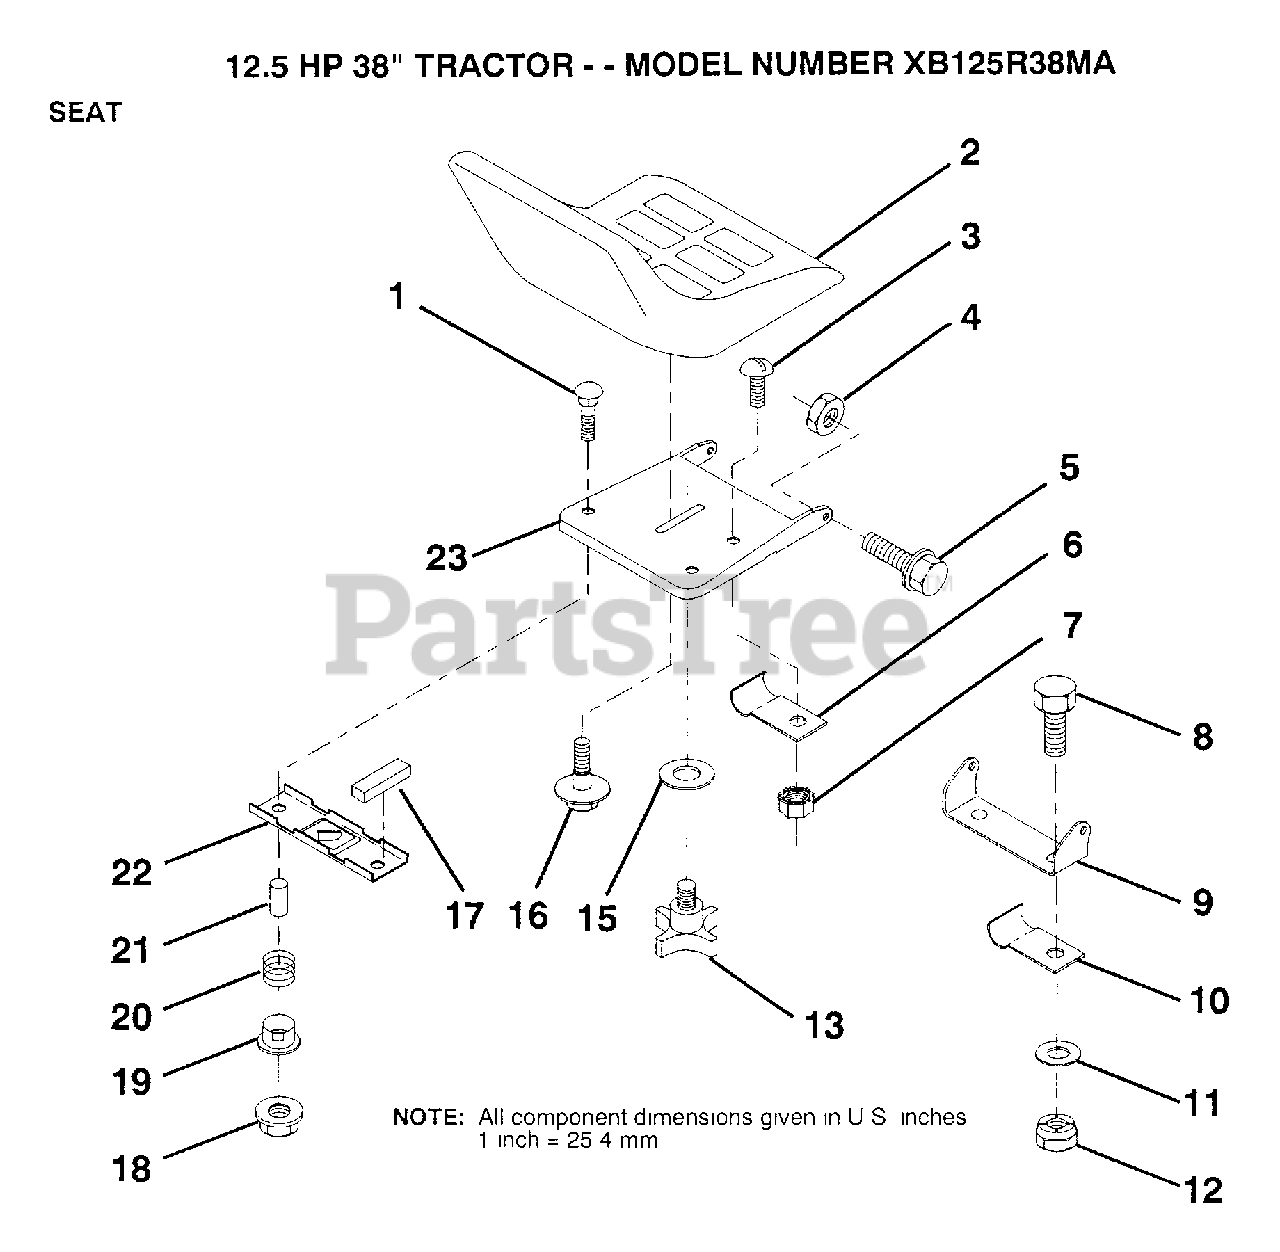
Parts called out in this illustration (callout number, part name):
7	"NUT,KEPS"
10	"CLIP,INSULATOR"
11	WASHER
13	"KNOB 1/2"" YT"
15	WASHER
16	"BOLT,SHOULDER"
17	STRIP FORM
19	BUSHING
20	SPRING
21	SPACER SPLIT
22	BRKT SWITCH
